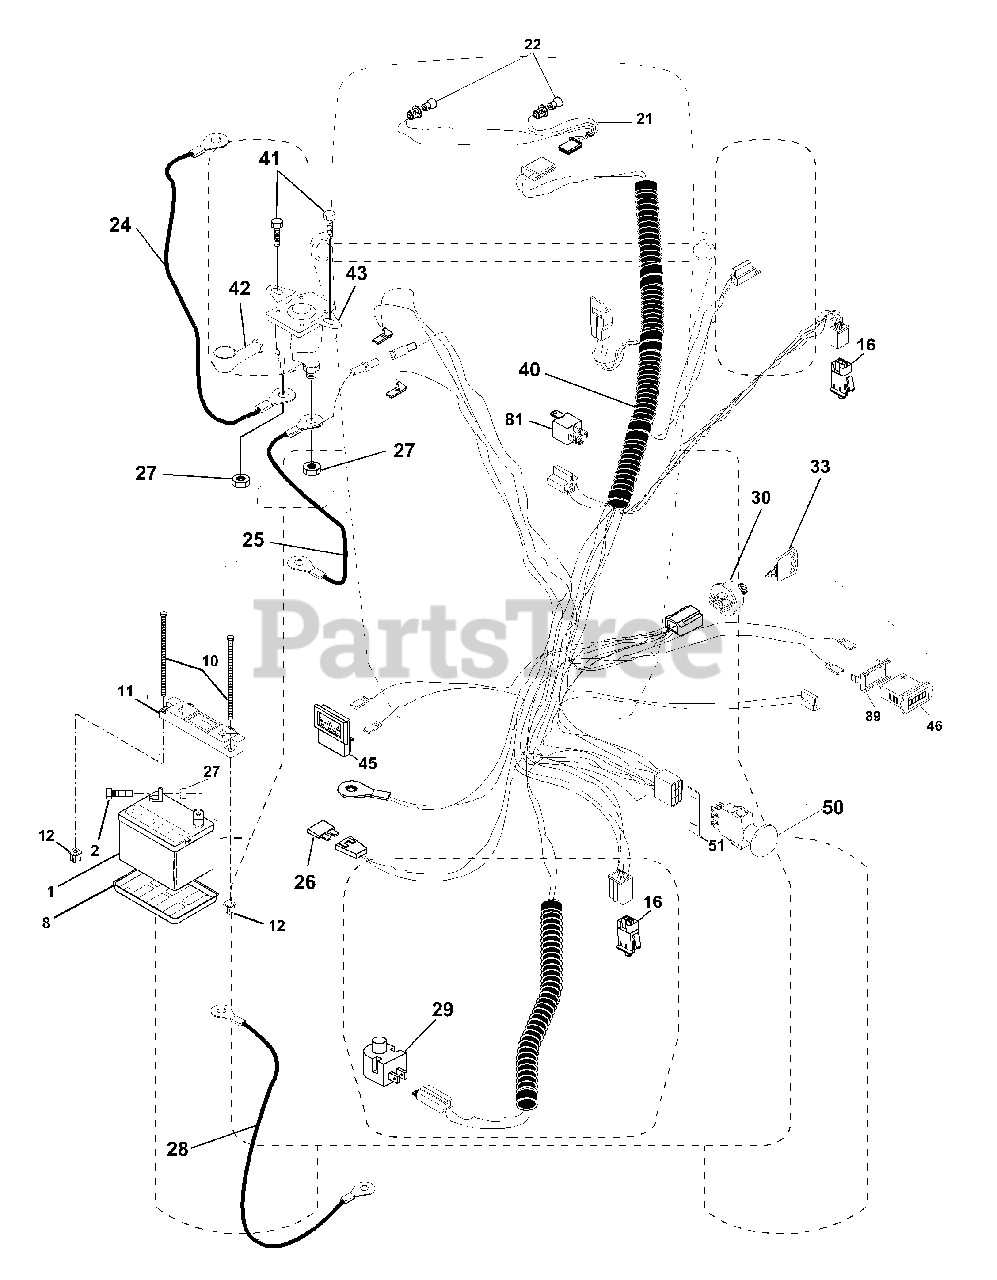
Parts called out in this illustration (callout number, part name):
1	Battery
2	Bolt Hex Head 1/4-20 x 3/4
8	Tray, Battery
10	Bolt Btr Frt 1/4-20 X 7.5 zinc
11	Holdown Battery Front Mount
12	Nut Push Nylon 1/4"
16	Switch Interlock Push-In
21	Harness Socket Light
22	Bulb Light
24	Cable, Battery
25	Cable, Battery
26	Fuse
27	Nut Keps Hex 1/4-20
28	Cable,Ground
29	Switch, Plunger
30	Switch, Ign
33	Key
40	Harness, Ignition
41	Screw 1/4-20 x 1/2
42	Cover, Terminal Red
43	Solenoid
45	Ammeter
46	Meter Hour
50	Switch, PTO
51	Ring Retainer PTO
70	Harness Engine
81	Relay Asm.
89	Bracket Snap-IN Hourmeter
